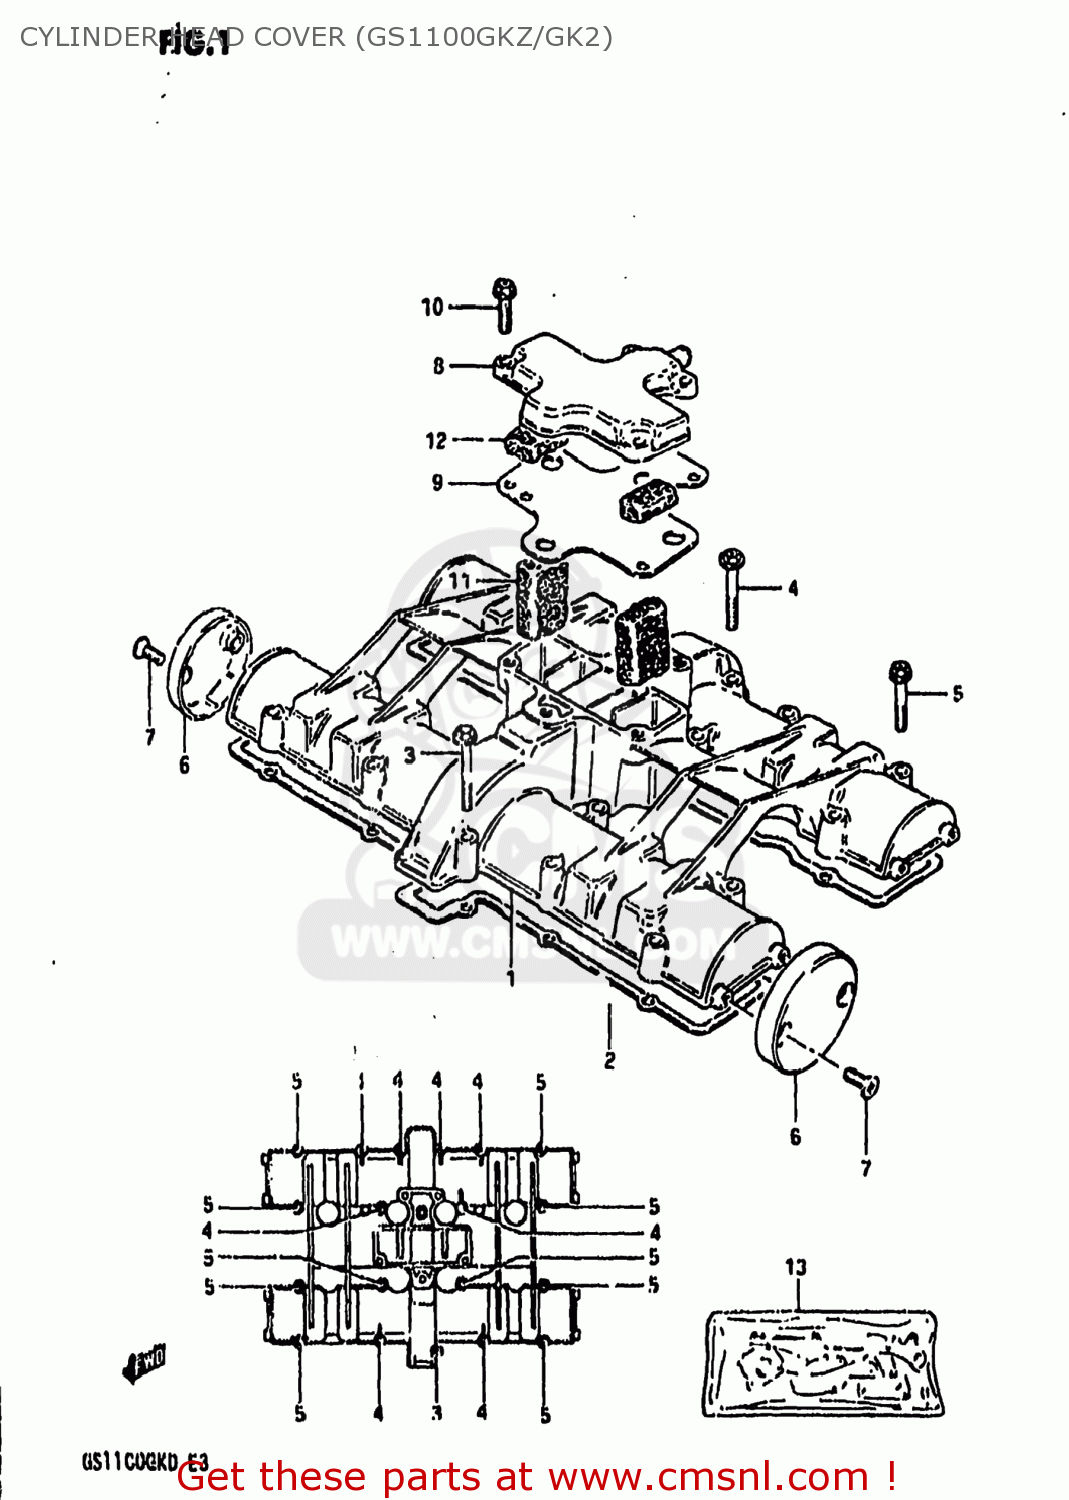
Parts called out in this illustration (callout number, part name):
1	COVER,CYLINDER HEAD
2	GASKET,CYLINDER HEAD COVER (MCA)
3	BOLT,UNDER
4	BOLT
5	BOLT 6X35
6	CAP,CYLINDER HEAD COVER
7	SCREW(5X12)
8	COVER,BREATHER
9	GASKET (MCA)
10	BOLT
11	COVER,BREATHER
12	SEPARATOR,OIL BREATHER
13	GASKET SET
